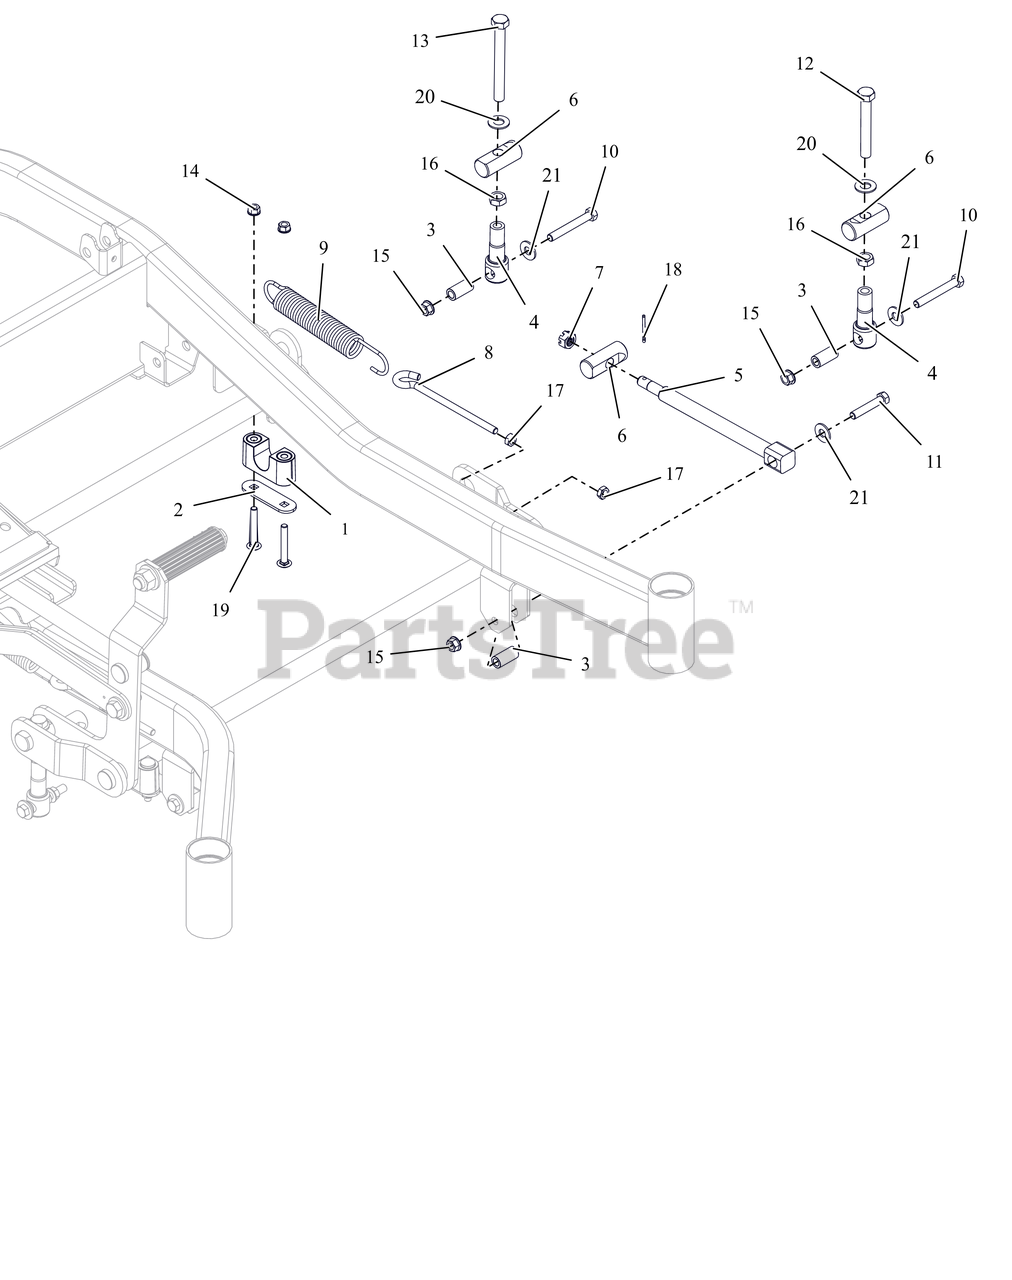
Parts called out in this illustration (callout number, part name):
1	ASM-BUSHING, DECK LIFT
2	PLATE, BEARING SUPPORT
3	SPACER, DECK LEVELING
4	LINK, DECK LIFT FORMED
5	DRAG,LINK-HD
6	PIN, DECK LIFT
7	NUT-SL .50-13
8	BOLT,.38-16 X 5.25-.62 DIA EYE
9	SG-TENS .162X1.25X8.25 WLD 25
10	BLT, HEX .38-16X2.75 G8 ZCC
11	BLT,HEX .38-16X2.00 G5 ZCC
12	BLT, HEX .50-13X3.50F G5 ZCC
13	BLT, HEX .50-13X4.50F G8 ZCC
14	NUT,LK-CTR-FLG .31-18 GF ZCC
15	NUT-LK-TOP-FLG .38-16 ZC120
16	NUT-JAM .500-13 G2 ZCC
17	NUT-JAM .375-16 G2 ZCC
18	PIN,CTR.12X1.25EXTPRSQCT ZC120
19	BLT, RHSSN.31-18X2.25 G5 ZCC
20	WSHR, FLT .557X1.040X.102 ZCC
21	WSHR,FLT .438X1.00X.083 ZCC
